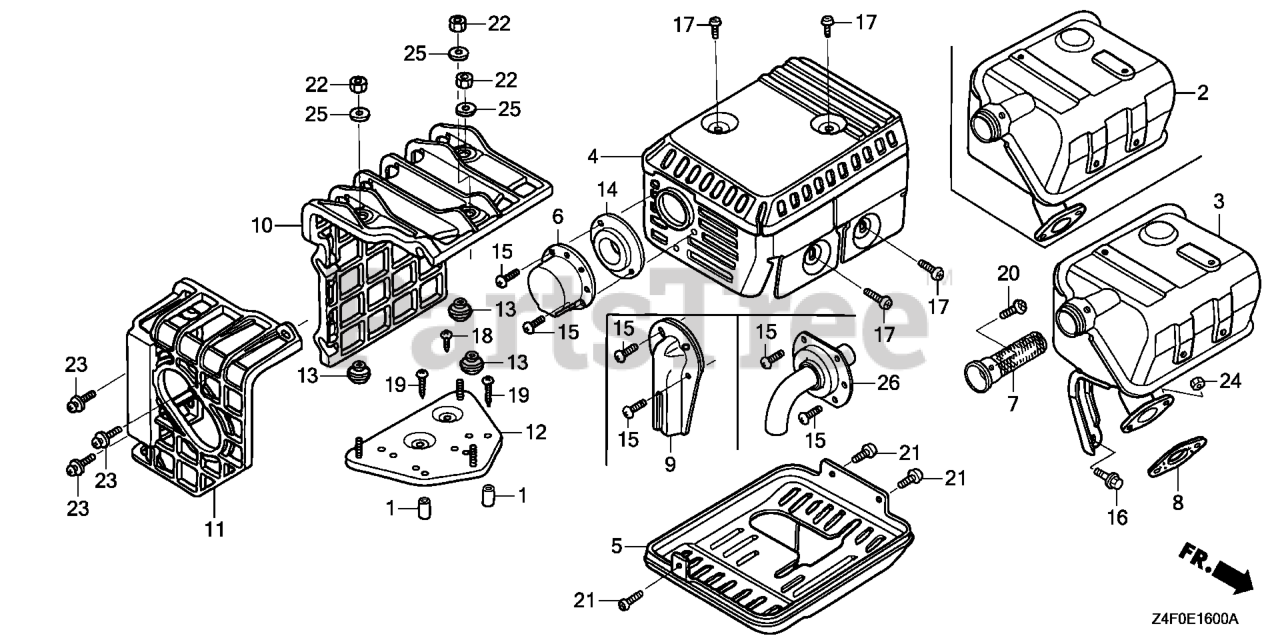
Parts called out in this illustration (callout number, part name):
2	MUFFLER (ARRESTER) (SPARK ARRESTER TYPE)
4	PROTECTOR, MUFFLER (STD) (BLACK)
6	DEFLECTOR
7	ARRESTER, SPARK
8	GASKET, MUFFLER
14	GUIDE, MUFFLER
15	SCREW, TAPPING (4X8)
16	BOLT, FLANGE (6X13)
17	SCREW, TAPPING (5X8)
20	SCREW, TAPPING (4X6) (TO INSTALL OPTIONAL SPARK ARRESTER)
24	NUT, HEX. (8MM)
